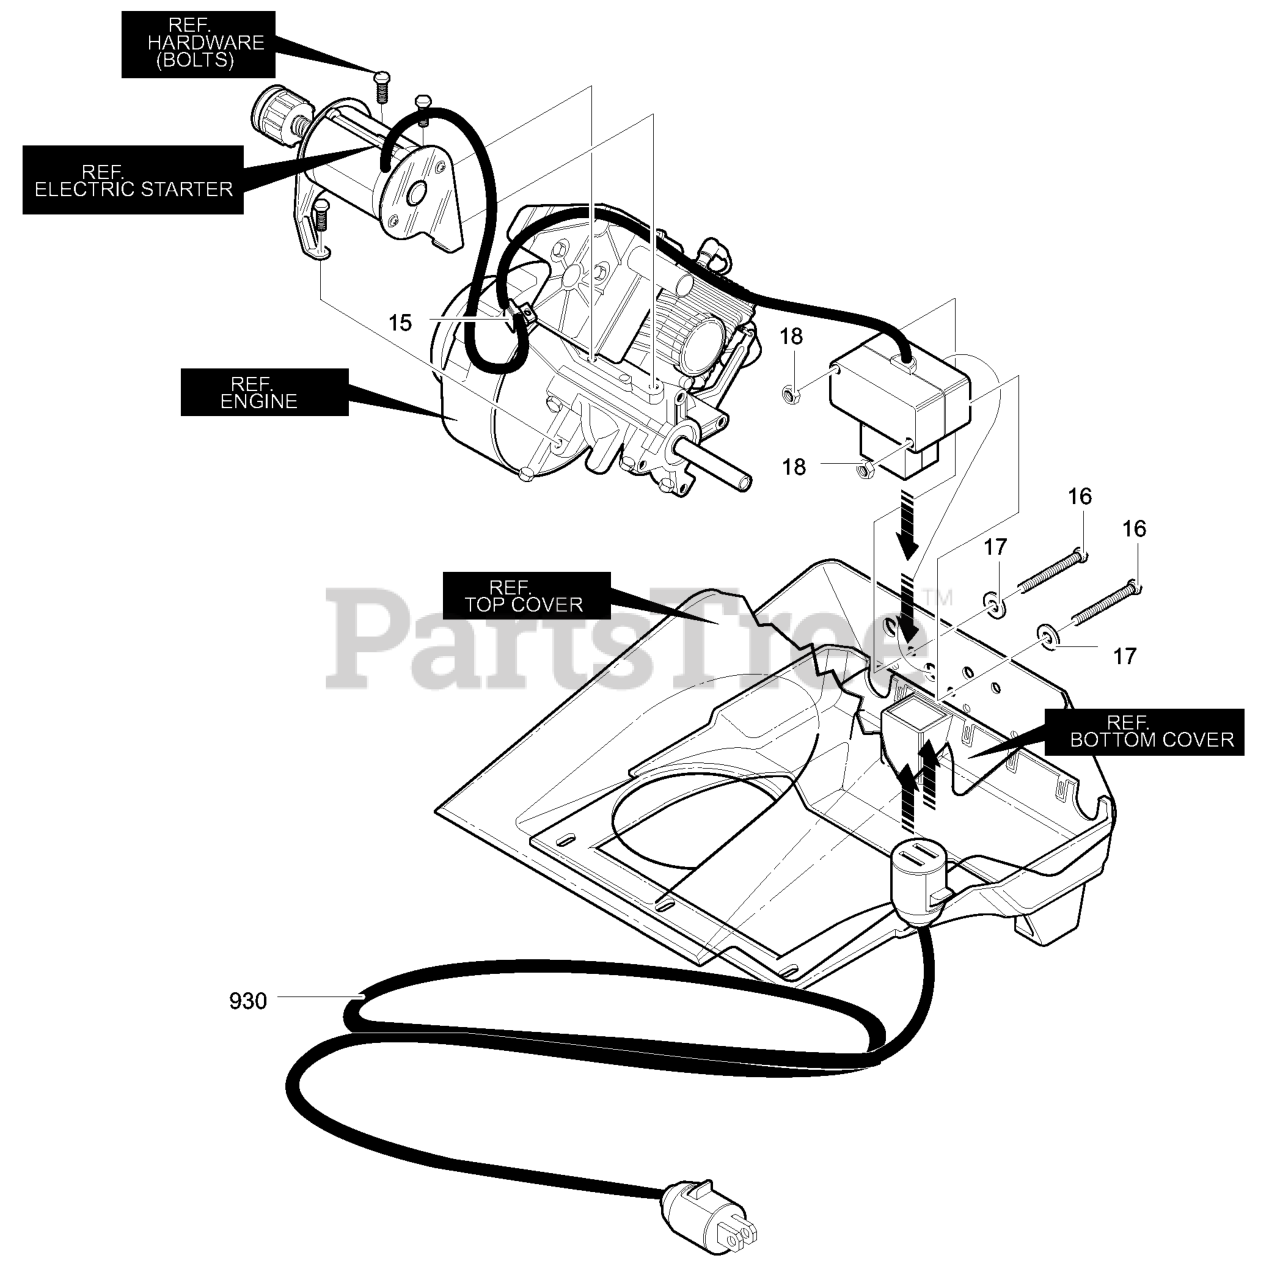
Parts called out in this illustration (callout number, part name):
15	RETAINER
16	SCREW #8-32X3.00
17	WASHER, FLAT .188X.38X.040
18	NUT, #8-32X3.00
930	CORD EXTENSION
